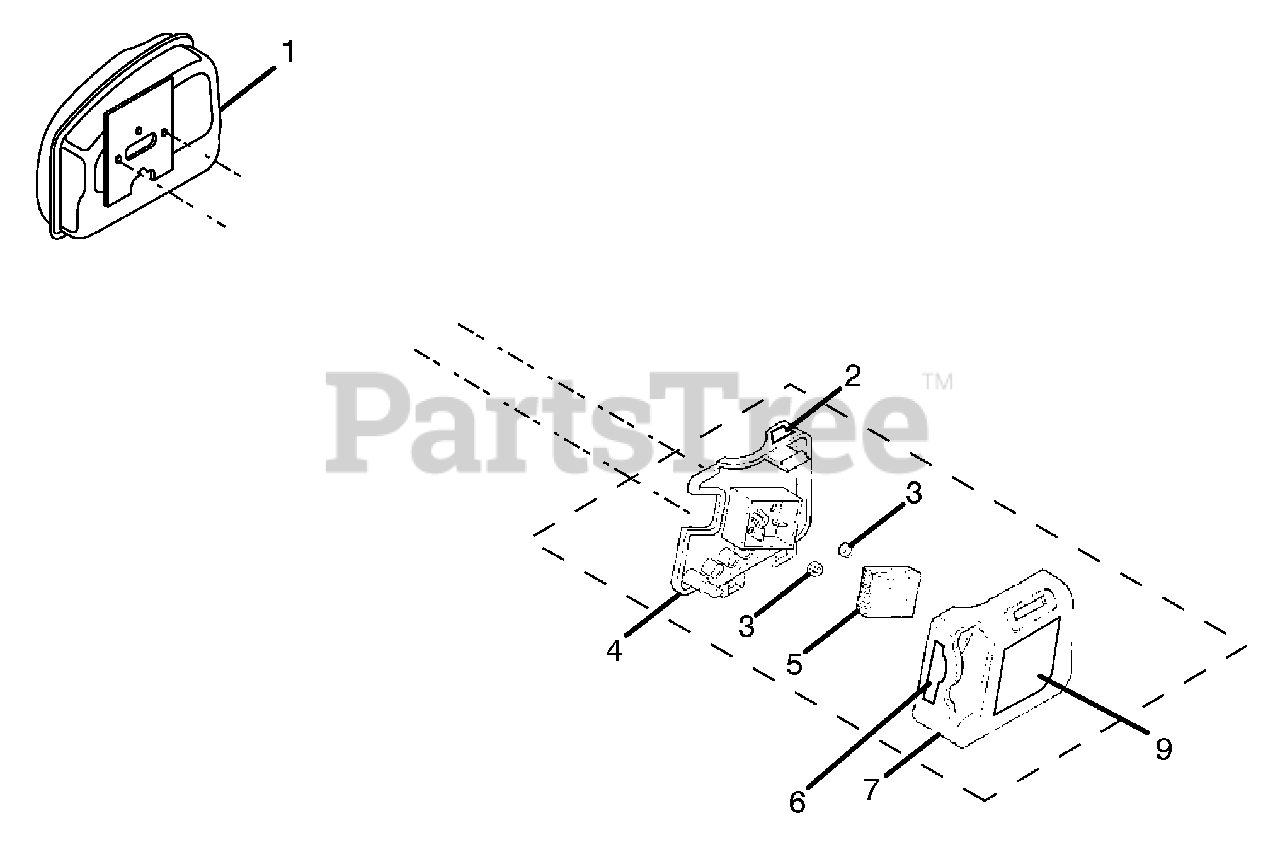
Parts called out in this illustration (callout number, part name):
1	MUFFLER ASSEMBLY
2	DECAL, PRIMER
3	LOCK NUT (10-24)
4	BOX AIR FILTER (CONEHEAD)
5	AIR FILTER
6	DECAL, STARTING INST
7	AIR BOX COVER
9	LABEL, AIRBOX AUTOZIP
